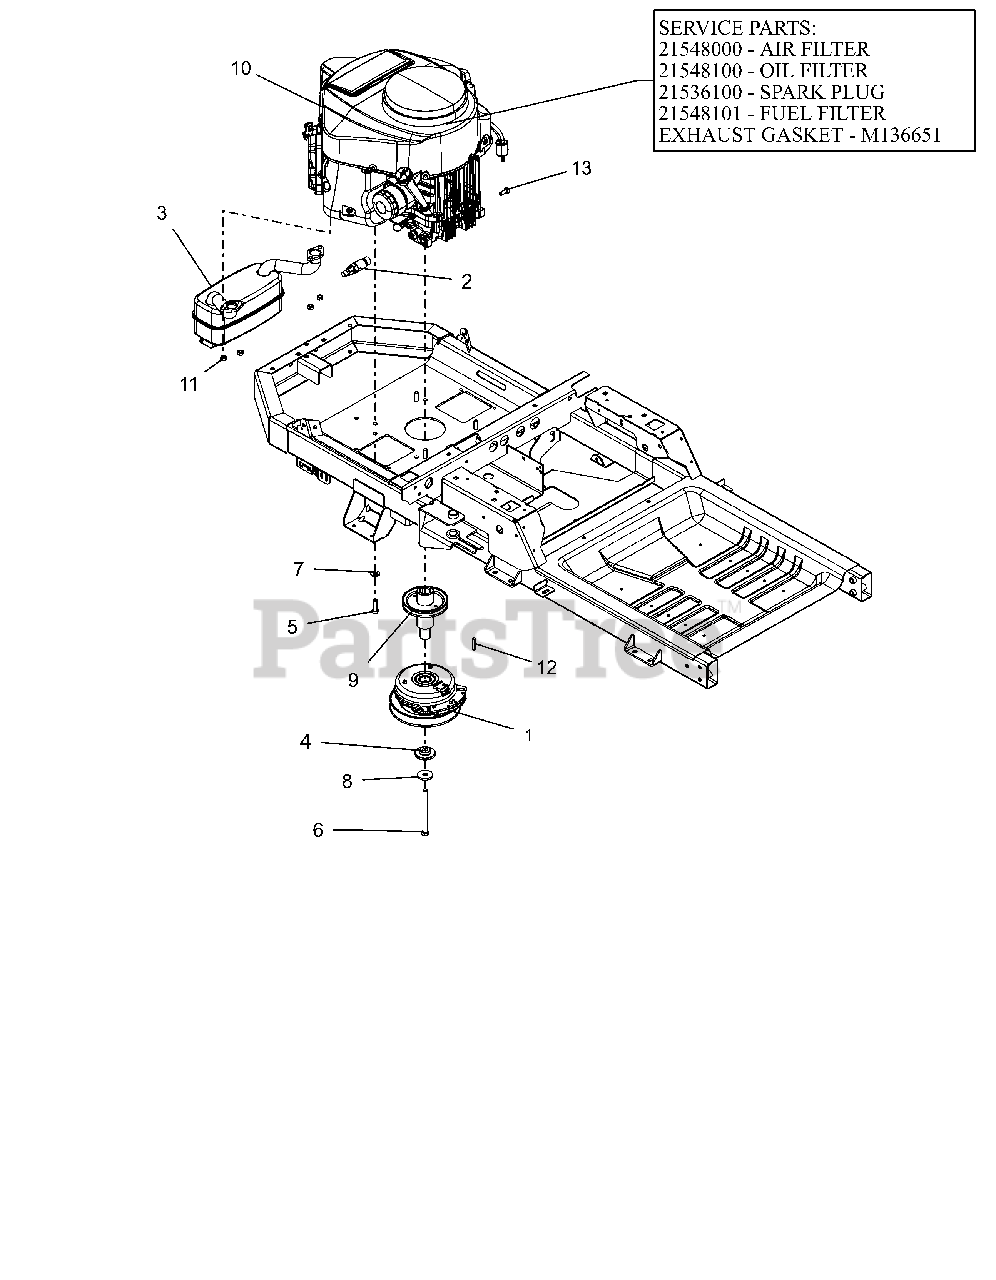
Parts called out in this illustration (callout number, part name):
1	CLUTCH,105FTLB MONOPOLE 6.83"
2	DRAIN, OIL M20X2.5
3	MUFFLER, KAWASAKI
4	BSHG-FLG .469X1.06X.574X2.0
5	BLT-HEX.38-16X1.25 G5YZ NYTORQ
6	BLT-HEX.438-20X5 GR8 YZ NYTORQ
7	WASHER, 3/8" SPRING DISC
8	WASHER, 7/16" SPRING DISK
9	WLDMT, DRIVE SHEAVE (LG XL)CZC
10	ENGINE, KAWASAKI FR691 23HP
10	AIR FILTER, KAWASAKI FR
10	OIL FILTER, KAWASAKI FR
10	PLUG, SPARK
10	FUEL FILTER-KAWASAKI FR
10	GASKET, MUFFLER #
11	NUT-LK-TOP M8-1.25 YWZC
12	KEY-SQ .25 X 1.25 X .25 SAE
13	BLT, HEX M8-1.25X20 G8.8 ZCC
